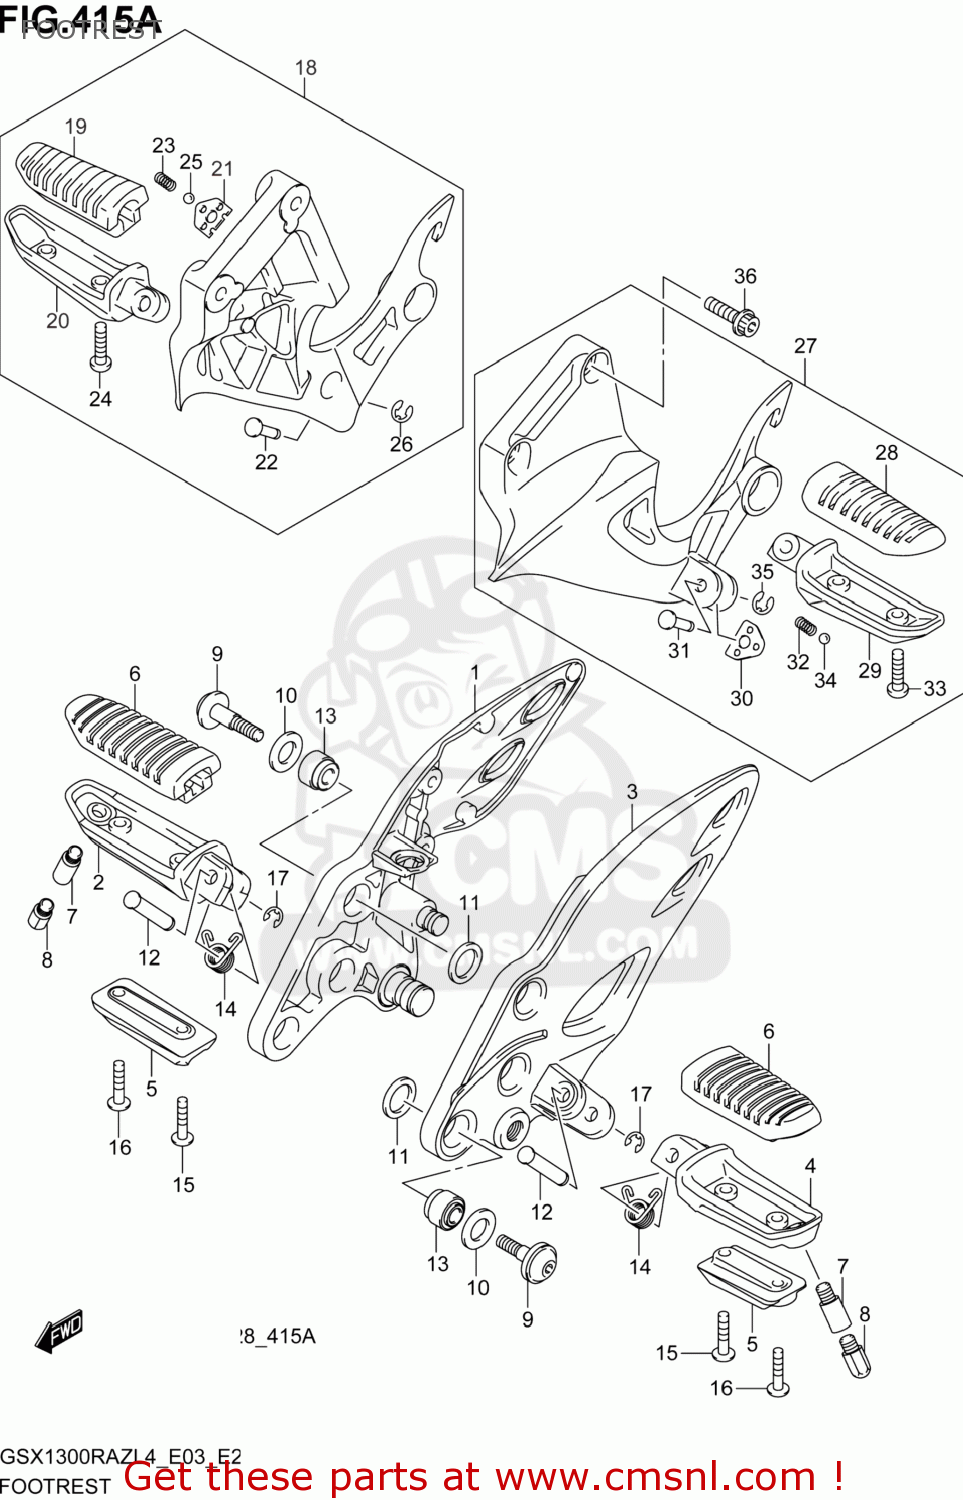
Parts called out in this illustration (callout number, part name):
1	BRACKET,FR FOOTREST,R
2	BAR,FR FOOTREST,R
3	BRACKET,FR FOOTREST,L
4	BAR,FR FOOTREST,L
5	BALANCER,FR FOOTREST
6	RUBBER,FOOTREST BAR
7	SENSOR,FOOTREST
8	SENSOR,FOOTREST
9	BOLT(8X30)
10	WASHER(13.7X24X2)
11	WASHER(17.2X24X2.2)
12	PIN
13	BUSH(8.4X20X16)
14	SPRING
15	SCREW
16	SCREW
17	E RING
18	FOOTREST ASSY,PILLION,R
19	RUBBER,FOOTREST
20	BAR,PILLION FOOTREST,R
21	PLATE,PILLION FOOTREST
22	PIN
23	SPRING
24	SCREW
25	BALL
26	E RING
27	FOOTREST ASSY,PILLION,L
28	RUBBER,FOOTREST
29	BAR,PILLION FOOTREST,L
30	PLATE,PILLION FOOTREST
31	PIN
32	SPRING
33	SCREW
34	BALL
35	E RING
36	BOLT(8X30)
